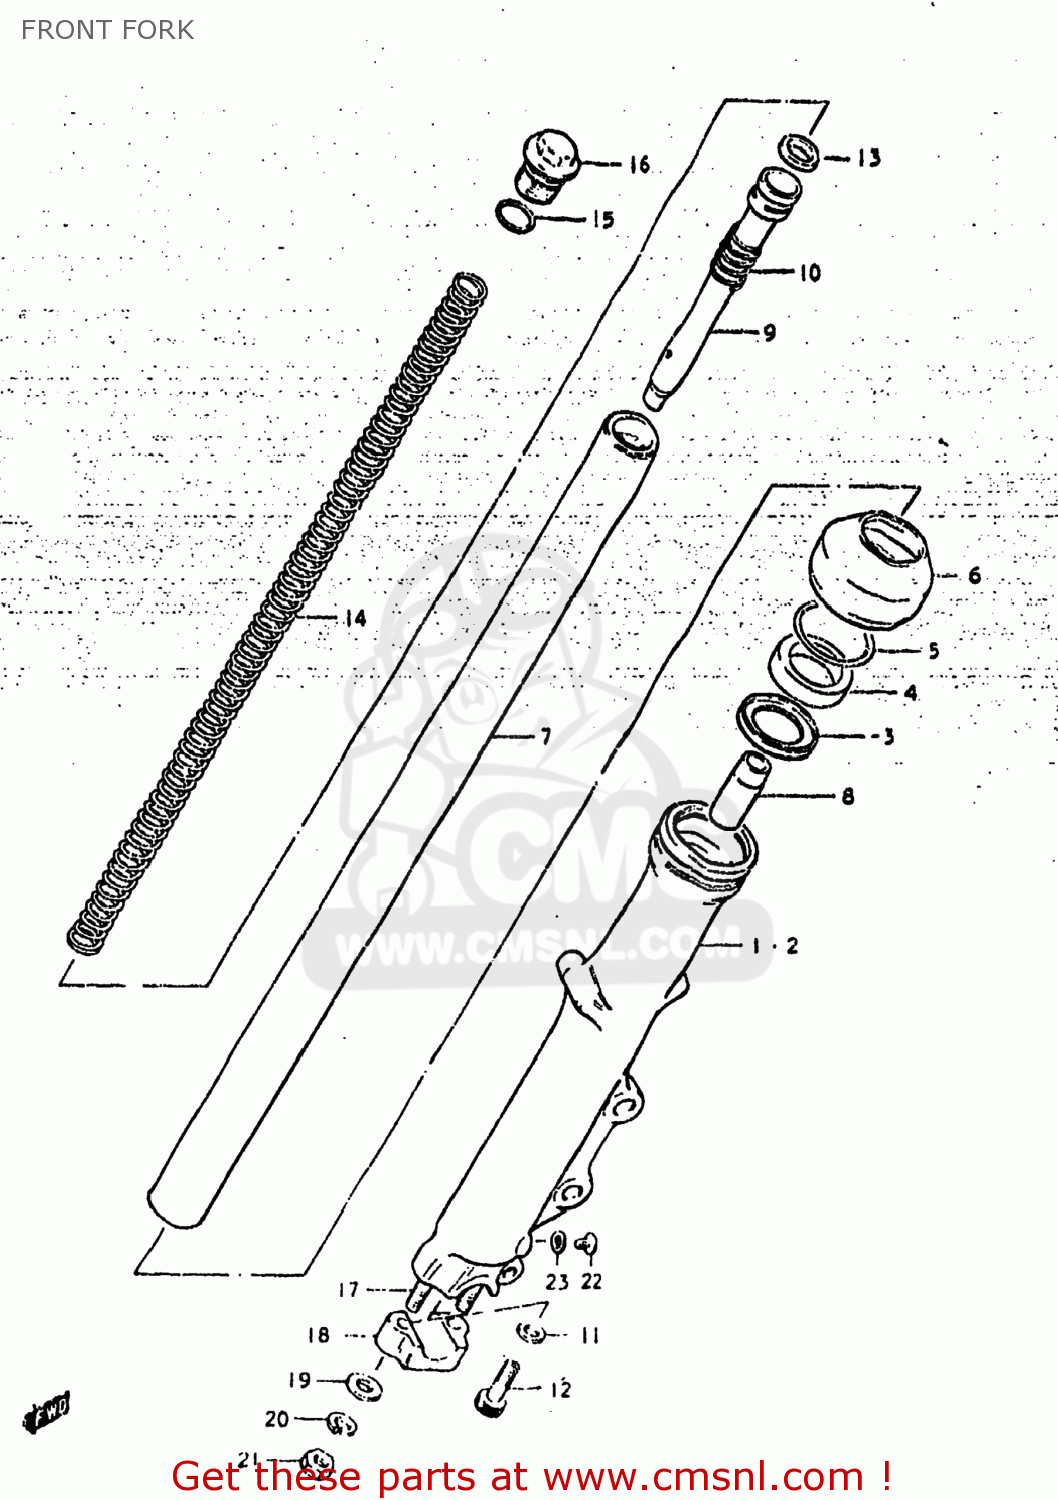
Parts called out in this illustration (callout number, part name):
0	DAMPER ASSEMBLY,LEFT
1	TUBE,FORK,OUTER,RIGHT
2	TUBE,FORK,LEFT,OUTER
3	SPACER,OIL SEAL
4	OIL SEAL,FRONT FORK
5	CIRCLIP,FORK OIL SEAL
6	BOOT
7	TUBE,FORK,INNER
8	PIECE,OIL LOCK
9	CYLINDER,FRONT FORK
10	SPRING,REBOUND
11	GASKET (NAS)
12	BOLT(8X27)
13	RING,PISTON
14	SPRING
15	O RING
16	BOLT
17	STUD 8X25
18	HOLDER,AXLE
19	WASHER
20	LOCK WASHER
21	NUT (8MM)
22	SCREW
23	GASKET (NAS)
